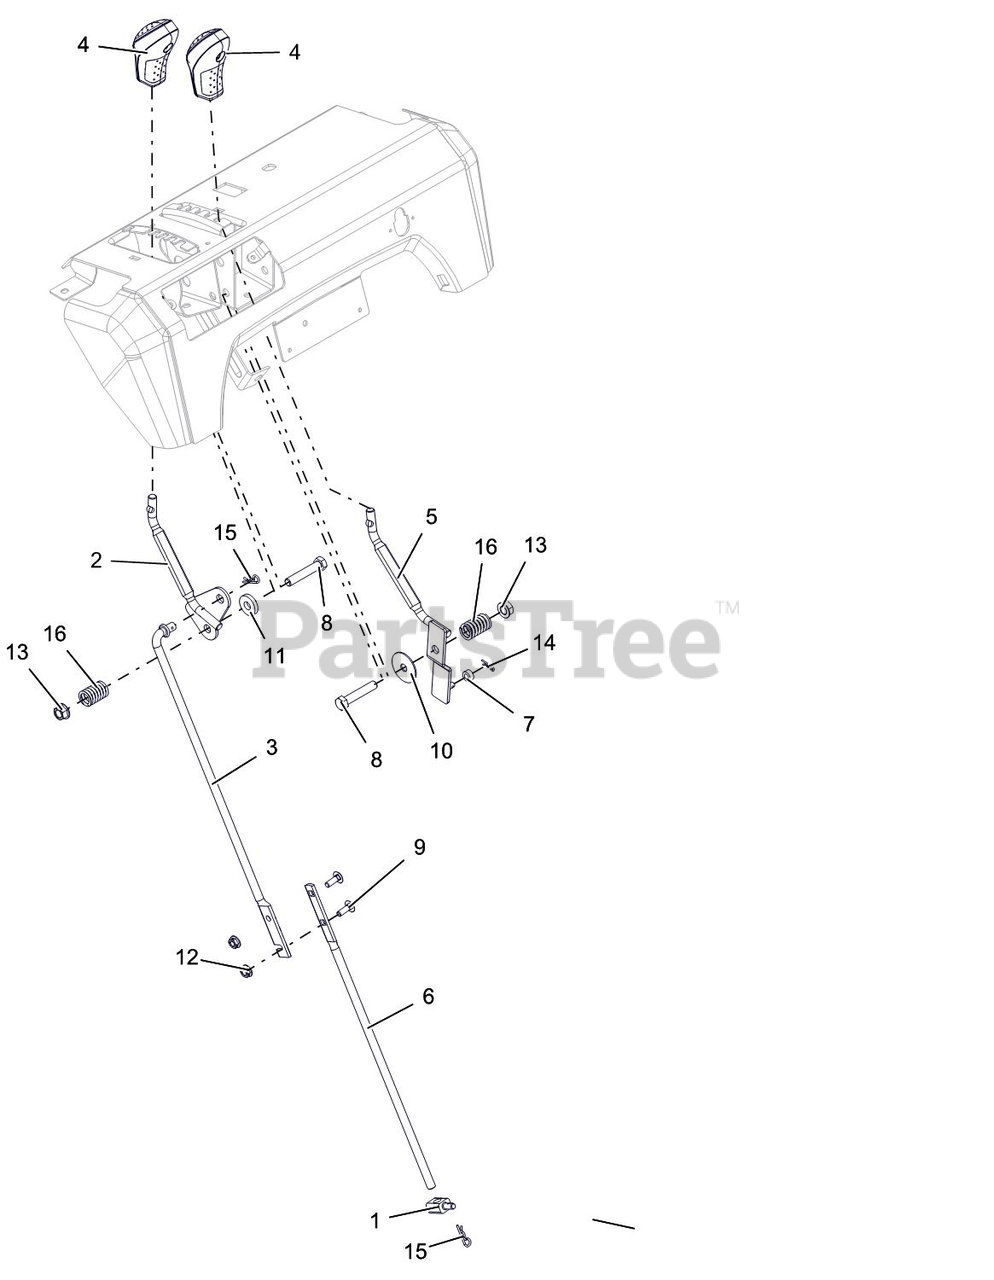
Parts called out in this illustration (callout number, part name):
1	PIVOT,SHIFT ROD .375-16(TRUNN)
2	WELDMENT,LG DASH SPEED CONTROL
3	ROD, SHIFT - UPPER
4	KNOB, CONTROL, DASH
5	WELDMENT,LG DASH DEFL CONTROL
6	ROD, SHIFT-LOWER (LG DASH DLX)
7	BSHG-SLV .265X.500X.219
8	@BLT-HEX .38-16X2.00 GR5 YWZC
9	@BLT-RDHDSQNK .25-20X.75 G5YZ
10	WSHR-FL-STL .380X1.50X.062 YWZ
11	WSHR-FL-STL .406X1.00X.188 YWZ
12	@NUT-LK-CTR-FLG .25-20 YWZC
13	@NUT-LK-TOP-FLG .38-16 YWZC
14	PIN-HAIR INT .06X.18X.77
15	PIN-HAIR INT .08X.18X1.18 YWZC
16	SG-COMP .125X.781X1.250
